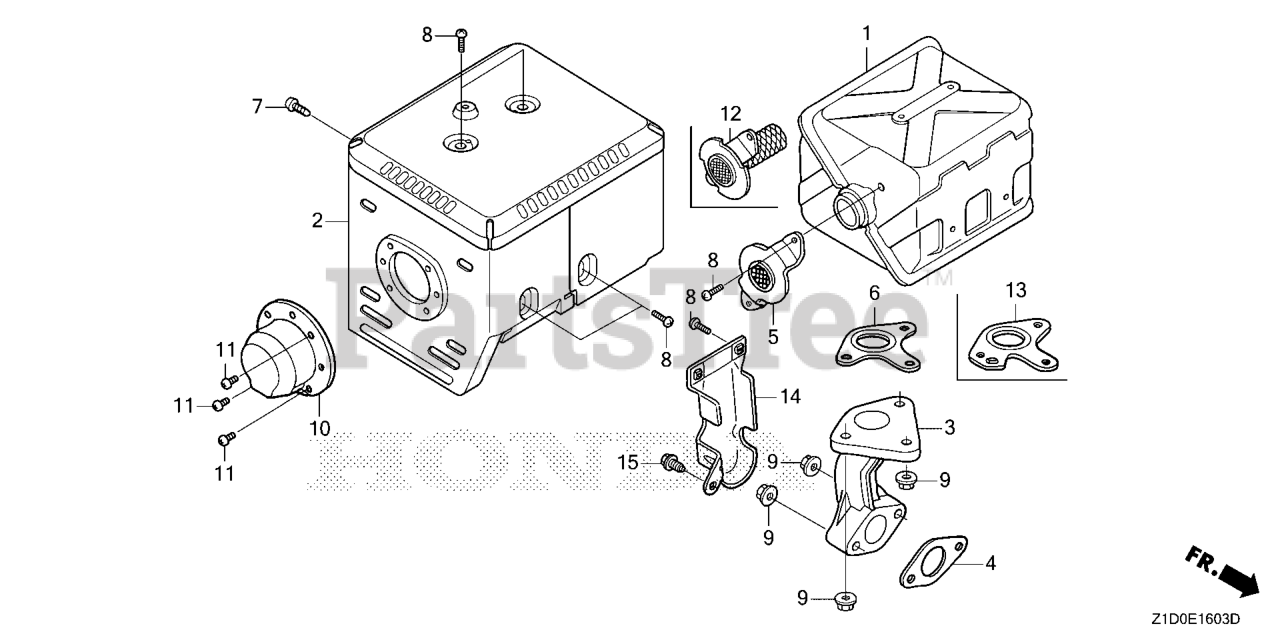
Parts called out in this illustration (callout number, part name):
1	MUFFLER
2	PROTECTOR, MUFFLER
4	GASKET, EX. PIPE
5	FLANGE, BAFFLE
6	GASKET, MUFFLER (NIPPON LEAKLESS)
6	GASKET, MUFFLER (THAI LEAKLESS)
7	SCREW, TAPPING (6X10)
8	SCREW, TAPPING (5X8)
9	NUT, FLANGE (8MM)
12	ARRESTER, SPARK
13	GASKET, MUFFLER (ARRESTER)
14	PROTECTOR, EX. PIPE
15	BOLT, FLANGE (6X12) (CT200)
